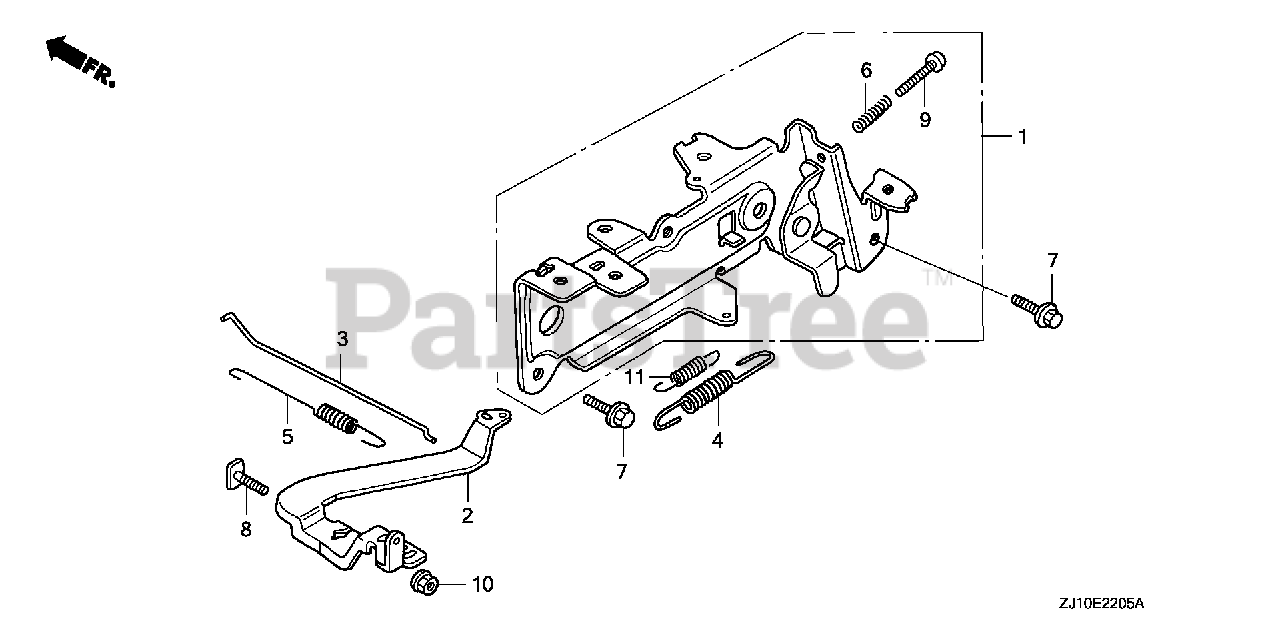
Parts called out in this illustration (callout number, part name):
1	CONTROL ASSY. (GENE)
2	ARM, GOVERNOR
3	ROD, GOVERNOR
4	SPRING, GOVERNOR
5	SPRING, THROTTLE RETURN
6	SPRING, CONTROL ADJUSTING
7	BOLT, FLANGE (6X14) (CT200)
8	BOLT, GOVERNOR ARM
9	SCREW, PAN (5X35)
10	NUT, FLANGE (6MM)
11	SPRING, STARTER
